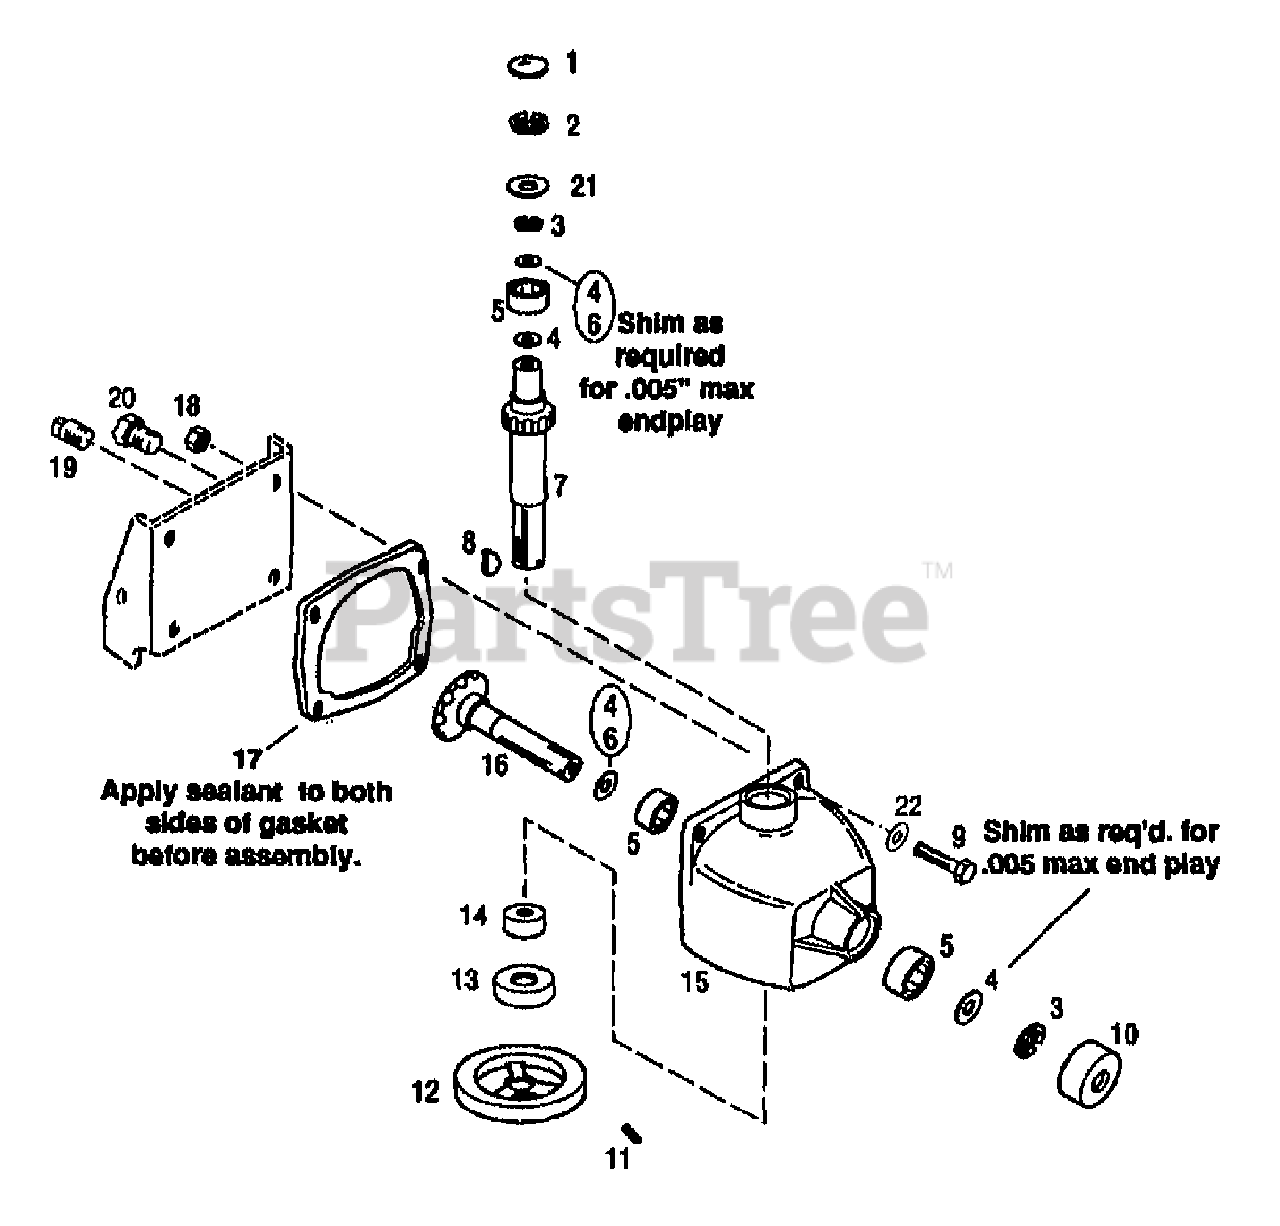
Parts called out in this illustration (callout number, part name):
1	PLUG-EXPANSION
2	RING-RETAIN INT 1.942 DIA
3	RING-RETAINING EXT .694 ID
4	SHIM-1.062X.789X.005
5	BEARING-BALL
6	SHIM-1.062X.789X.01
7	SHAFT-OUTPUT
8	KEY-WOODRUFF .188X.75
9	SCR-HH 5/16-18X1.25 G5ZP
11	SCR-SQ HD SET 5/16X3/4
12	SHEAVE-DRIVE
13	SEAL-OIL
14	BEARING-NEEDLE
15	CASE-GEAR
16	GEAR-BEVEL 26T
17	GASKET
18	NUT-TOP/LK 5/16-18 ZP
19	PLUG-PIPE
20	VALVE
21	SHIM-.005
22	WASHER-LK .312 ZP
